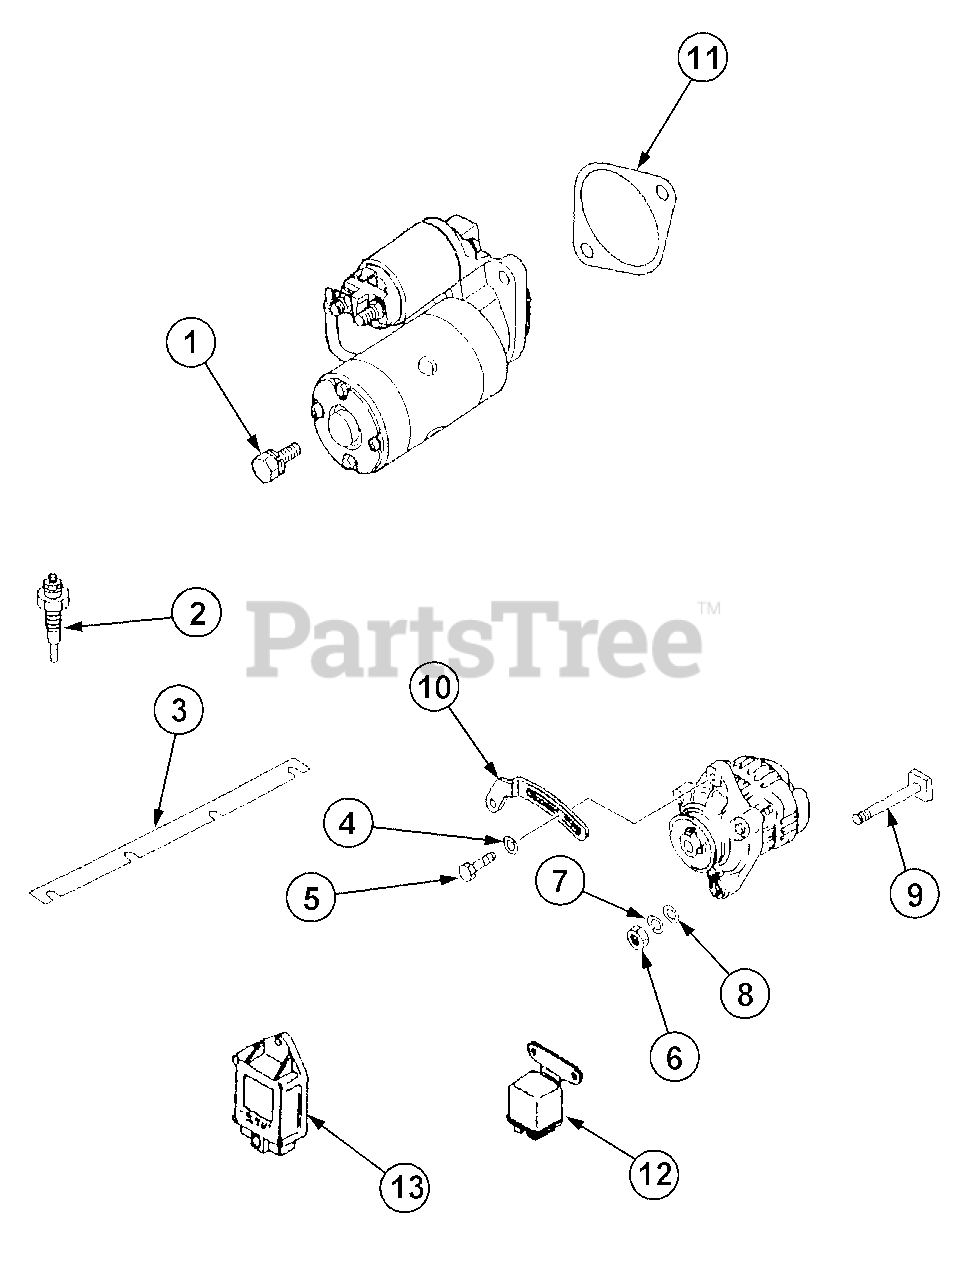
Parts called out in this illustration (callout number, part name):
1	Bolt, w/Washer
2	Plug, Glow
3	Plate, Connect
5	Bolt, Flange
7	Washer, Spring
8	Washer, Plain
9	Bolt, Alternator
10	Plate, Adjusting
11	Gasket, Starter
12	Relay Assy, Glow
13	Controler, Glow
